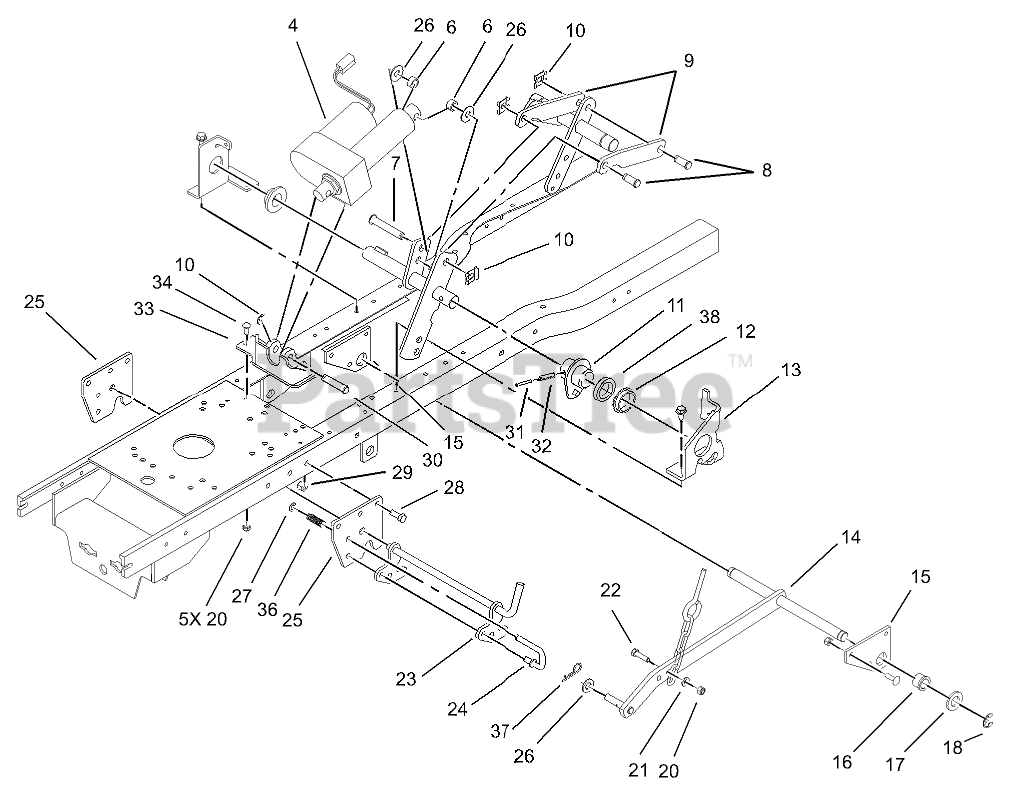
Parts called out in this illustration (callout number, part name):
4	ACTUATOR
6	SPACER
7	PIN-CLEVIS
8	PIN-CLEVIS
9	STRAP-LINK, LIFT
10	CLIP-PIN
11	END CAP ASM
12	BUSHING
13	BRACKET-ARM, LIFT
14	LIFT BAR ASM
15	Plate-Lift, Rear
16	BUSHING-FLANGE
17	WASHER-FLAT
18	E-RING
20	NUT-LOCK, NI
21	WASHER-PLAIN
22	SCREW-HH
23	MIDHITCH LATCH ASM
24	ROD-CATCH, MIDHITCH
25	Plate-Hitch
26	WASHER-FLAT
27	RING-RETAINING
28	SCREW-HH
29	NUT-LOCK, NI
30	PIN-CLEVIS
31	PIN-SPRING
32	PIN-ROLL
33	ACTUATOR BRACKET ASM
34	SCREW-CARR
36	SPRING
37	PIN-HAIR
38	SPACER
